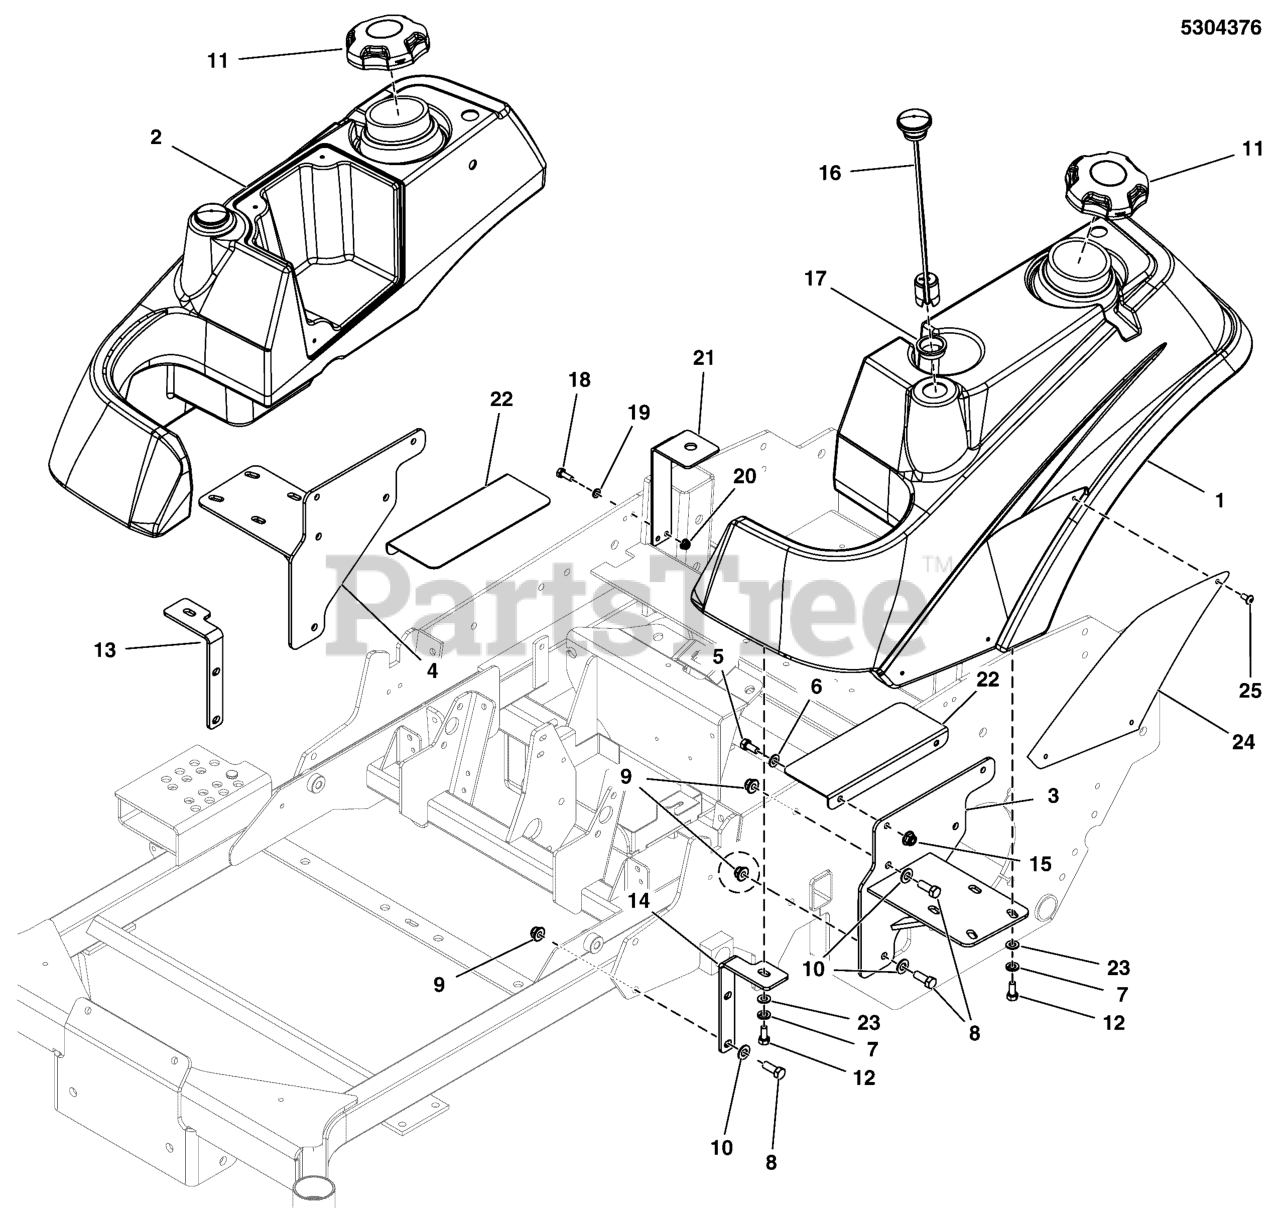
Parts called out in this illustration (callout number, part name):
1	TANK, FUEL, 5.75GAL, MED, Z-LH, LOW PERM
2	TANK, FUEL, 5.00GAL, MED, Z-RH, LOW PERM
3	WELD, FUEL TANK MOUNT, F160Z LH - RED
4	WELD, FUEL TANK MOUNT, F160Z RH - RED
5	BOLT, 5/16-18 X 1 GD5 CZ
6	WASHER, 5/16" SAE
7	WASHER, 5/16 LOCK CZ
8	BOLT, 3/8-16 X 1" GD5 CZ
9	NUT, 3/8-16 HEX NYLOCK FLANGE
10	WASHER, 3/8 SAE
11	FUEL CAP, 3-1/2", MANAGED VENT OUT, 12"
12	BOLT, 5/16-18 X 3/4 GD5
13	PLATE, FRONT TANK MOUNT, F160Z, RH - RED
14	PLATE, FRONT TANK MOUNT, F160Z, LH - RED
15	NUT, 5/16-18 HEX NYLOCK FLANGE
16	GAUGE, FUEL, 12
17	GROMMET, FUEL GAUGE
18	BOLT, 1/4-20 X 3/4 GD5 CZ
19	WASHER, 1/4 SAE
20	NUT, 1/4-20 HEX NYLOCK FLANGE
21	PLATE, FUEL SWITCH, F160Z - BLK
22	GUARD, FAN - BLK
23	WASHER, 5/16 F436 FLAT
24	PLATE, BADGE - IS1500 - RED
25	SCREW, #10-24 X 3/8 ALLEN BHBZ
